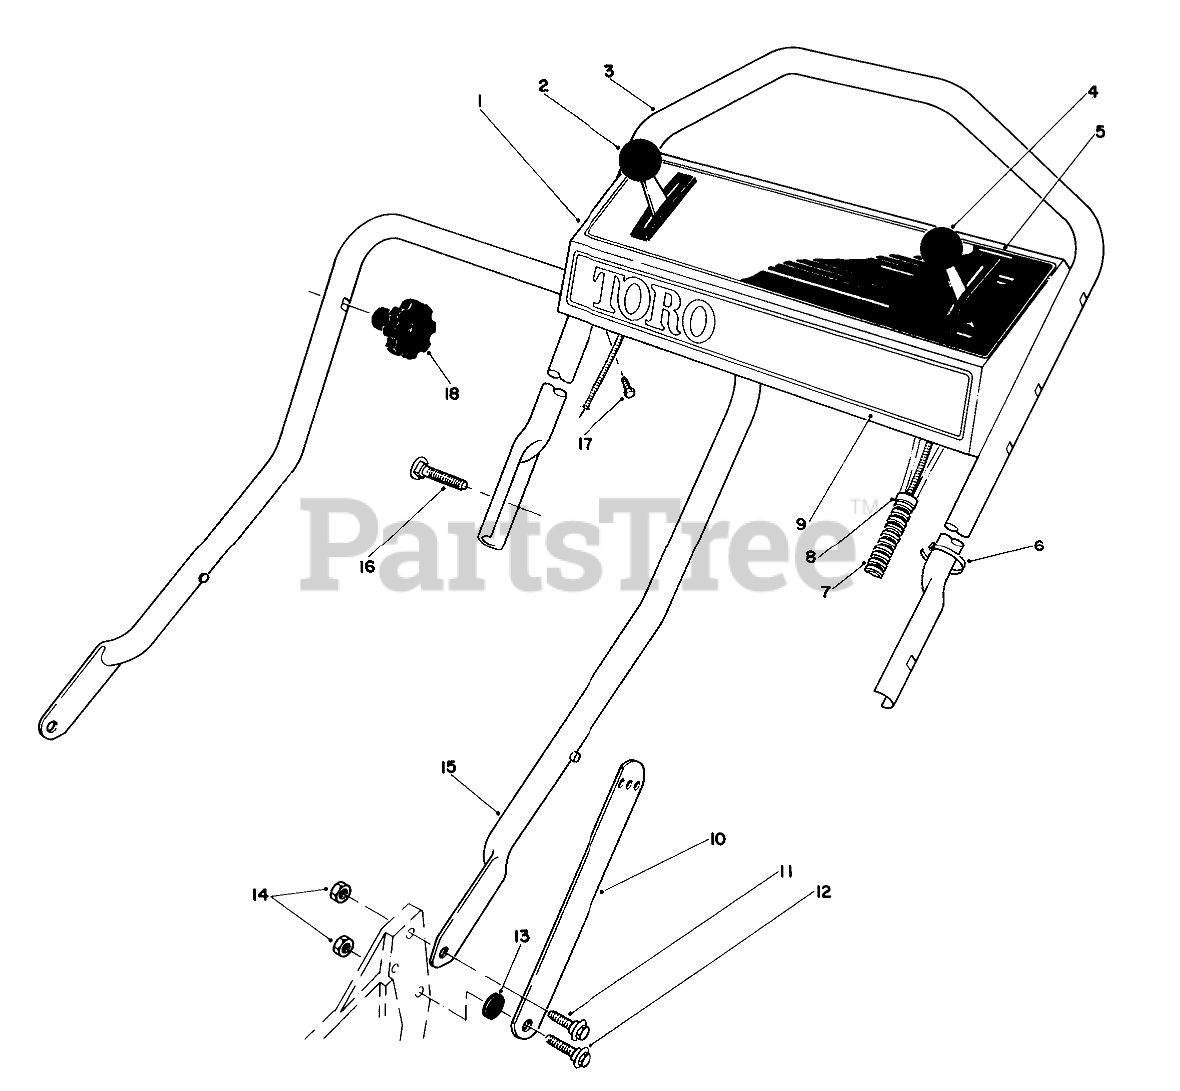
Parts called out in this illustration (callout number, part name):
1	Panel-Control (Incl. Ref. #5)
2	GROUND SPEED CONTROL
3	Handle-Upper
4	SERVICE THROTTLE CONTRO
5	Decal-Instruction Panel
6	TIE-CABLE
7	CONTROL CABLE COVER
8	FITTING-RING
9	Decal-Toro
10	Handle Latch
11	SCREW-SHOULDER
12	SCREW-SHOULDER
13	SPACER
14	NUT-LOCK, NI
15	Handle-Lower
16	5/16-18 X 2 HNDLE SCREW
17	SCREW-HWHTF
